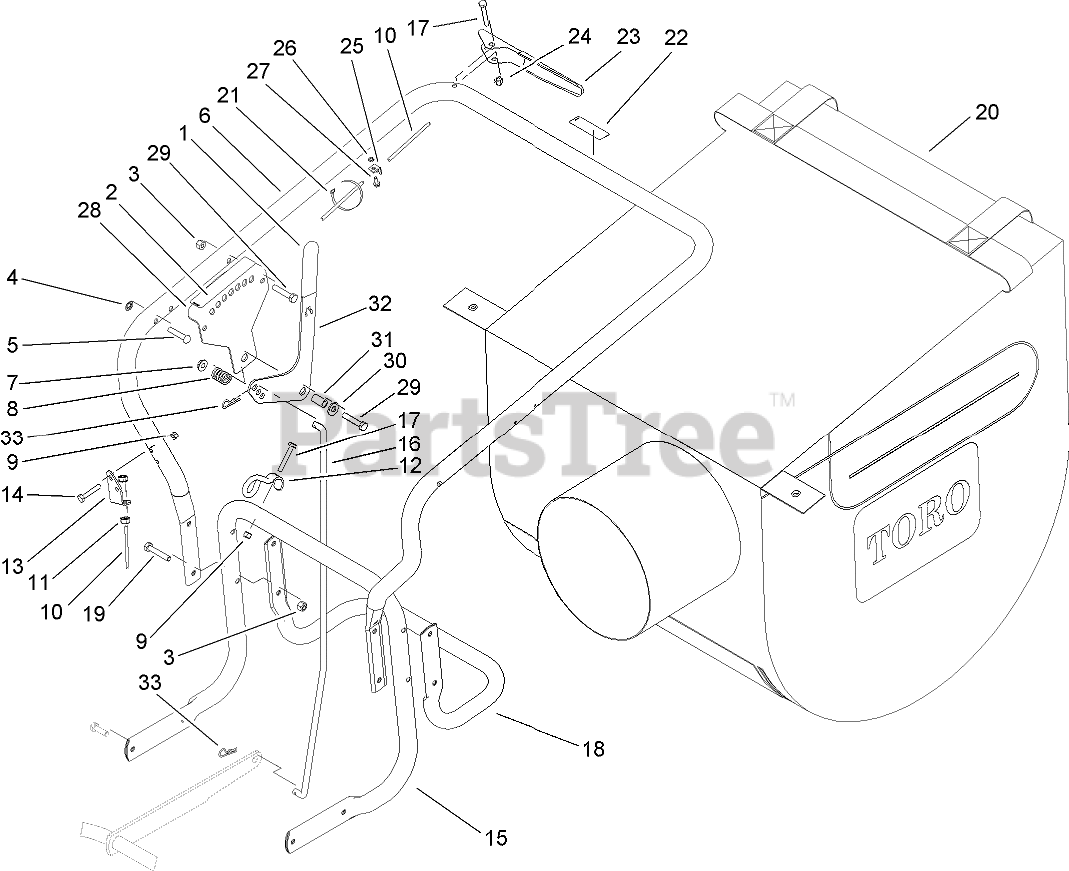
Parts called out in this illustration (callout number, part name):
1	GRIP-HANDLE
2	DECAL-ADJUSTMENT, HEIGHT
3	NUT-LOCK, NI
4	NUT-PUSH IN
5	RIVET
6	HANDLE-UPPER, VACUUM
7	NUT-HF
8	SPRING-COMPRESSION
9	NUT-LOCK, NI
10	CABLE-TRACTION
11	NUT-KEPS
12	GUIDE-ROPE
13	MOUNT-BOWDEN, LOWER
14	SCREW-HH
15	HANDLE-LOWER
16	ROD-ADJUST, HEIGHT
17	SCREW-HH
18	SUPPORT-BAG
19	SCREW-HH
20	Bag-Vacuum
21	TIE-CABLE
22	DECAL-CONTROL, TRACTION
23	LEVER
24	NUT-CAP
25	RETAINING-CLIP
26	WASHER-LOCK, EXT
27	SCREW-HWH
28	BRACKET-ADJUSTMENT
29	SCREW-HH
30	WASHER-FLAT
31	SPACER
32	HANDLE-ADJUST, HEIGHT
33	PIN-COTTER
